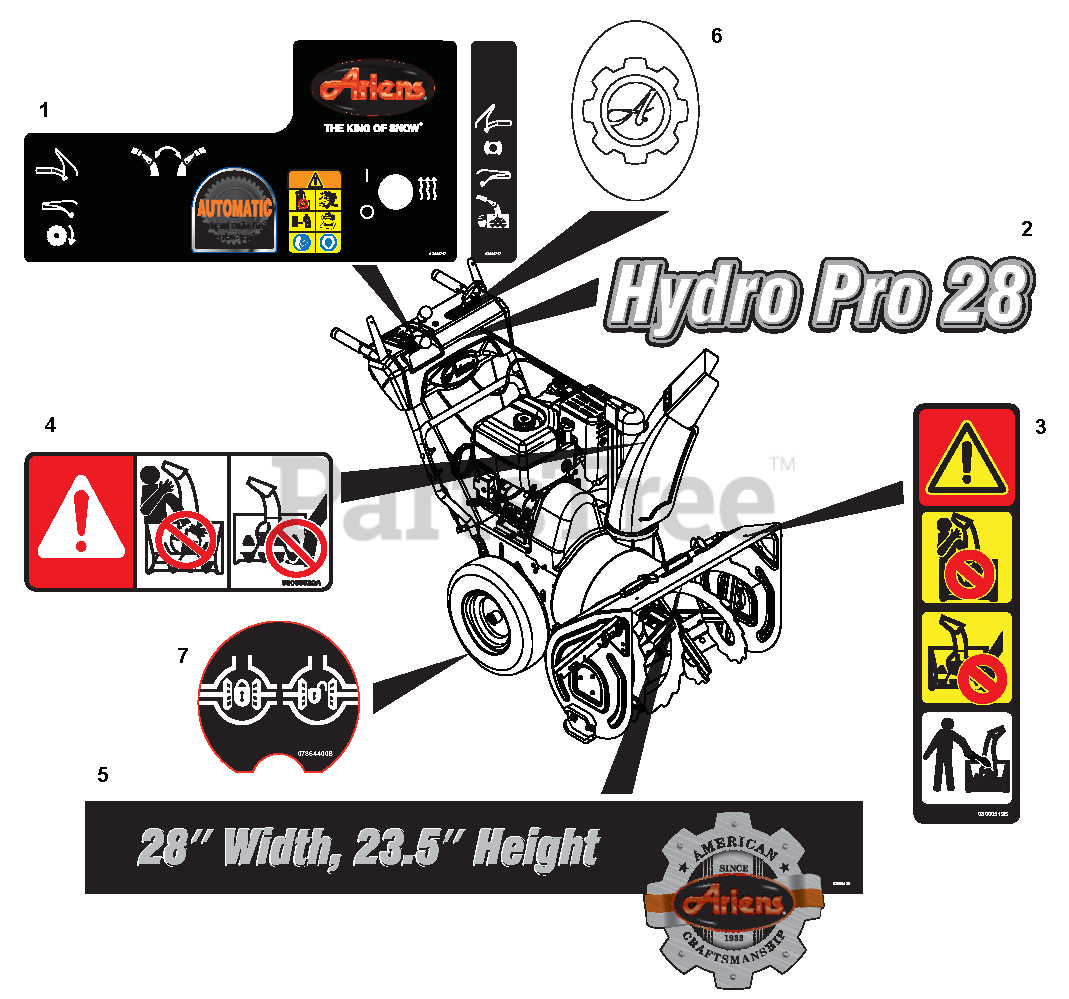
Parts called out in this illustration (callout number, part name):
1	DECAL, CONTROL - PLATINUM/PRO
2	DECAL, PRO HYDRO 28 DASH
2	DECAL, PRO HYDRO 32 DASH
3	DECAL, DANGER - ROTATING PARTS
4	DECAL, DANGER
6	DECAL, ARIENS GEAR - RAISED
7	DIFFERENTIAL LOCK DECAL
